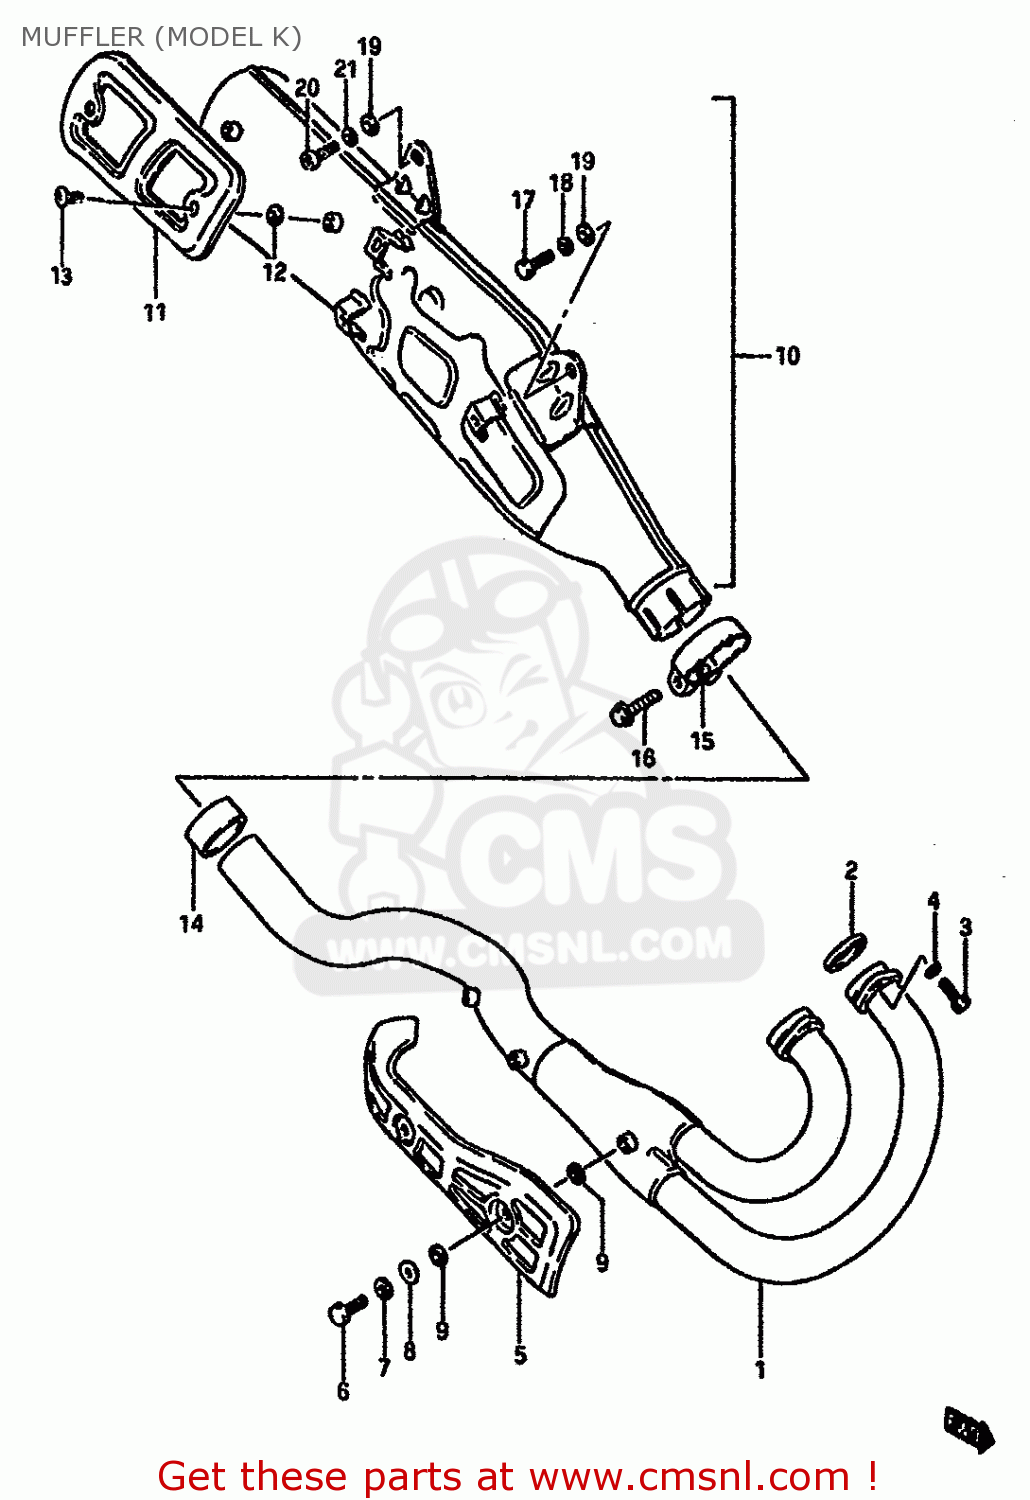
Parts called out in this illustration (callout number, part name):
1	PIPE,EXHAUST
2	GASKET,EXHAUST PIPE
3	BOLT
4	WASHER,LOCK
5	COVER,EXHAUST PIPE
6	BOLT
7	WASHER,LOCK
8	WASHER
9	GASKET
10	MUFFLER ASSY
11	COVER,MUFFLER
12	GASKET,EXHAUST PIPE
13	SCREW
14	CONNECTOR,MUFFLER
15	CLAMP,MUFFLER,R(L:42.7)
16	BOLT 8X40
17	BOLT
18	WASHER,LOCK,8.
19	WASHER
20	WASHER,LOCK,8.
21	WASHER
22	BOLT
23	LOCK WASHER
